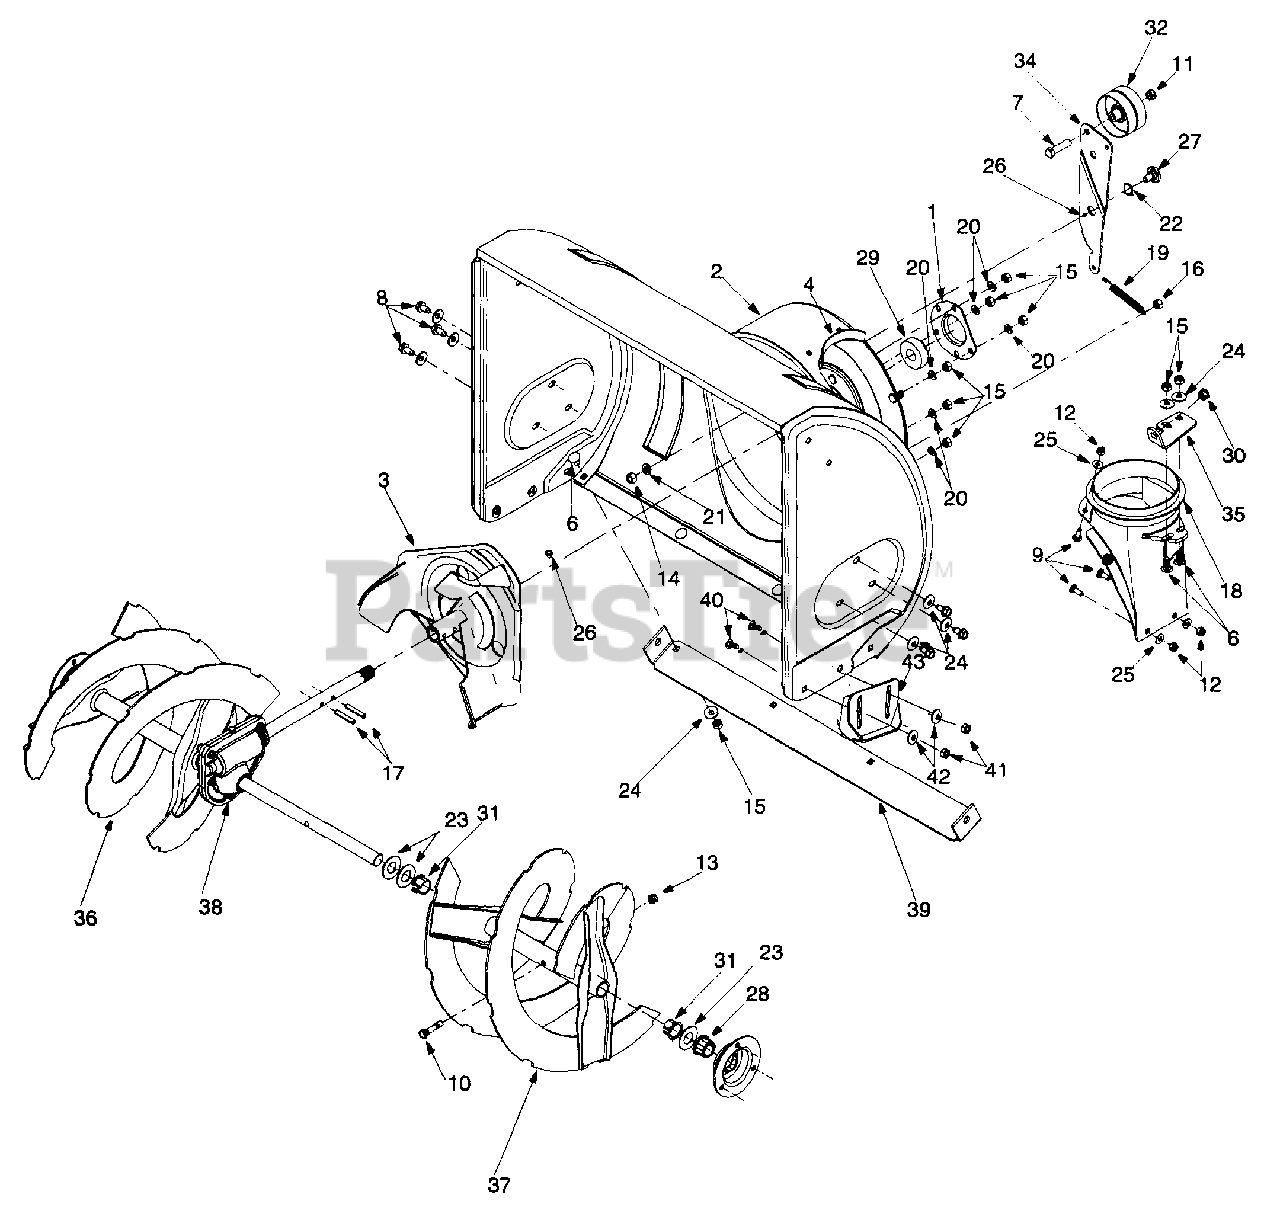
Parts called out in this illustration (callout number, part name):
1	Bearing Housing
6	Carriage Bolt 5/16-18 x .75" Gr.2
7	Hex Screw 3/8-24 x 1.5" Gr.5
8	Hex Washer Head Self-Tapping Screw 5/16-18 x .62"
9	Carriage Screw 1/4-20 x .75"
10	Shear Bolt 5/16-18 x 1.5"
11	Jam Nut 3/8-24
12	Hex Lock Nut 1/4-20
13	Hex Lock Nut 5/16-18
14	Hex Nut 3/8-16 Gr.2
15	Hex Nut 5/16-18 Gr.5
16	Hex Patch Nut 5/16-18
17	Spiral Pin
18	Chute Adapter
19	Extension Spring
20	Lock Washer
21	Lock Washer
22	Wave Washer
23	Flat Washer
24	Belleville Washer
25	Flat Washer
26	Grease
27	Shoulder Screw
28	Hex Flange Bearing
29	Flange Ball Bearing
30	Bushing
31	Flange Bushing
32	Flat Idler
38	Gear Assembly: Auger 28"
40	Carr. Bolt: 5/16-18 x 0.75
41	Hex Nut: 5/16-18 Gr.5
42	Belleville Washer
